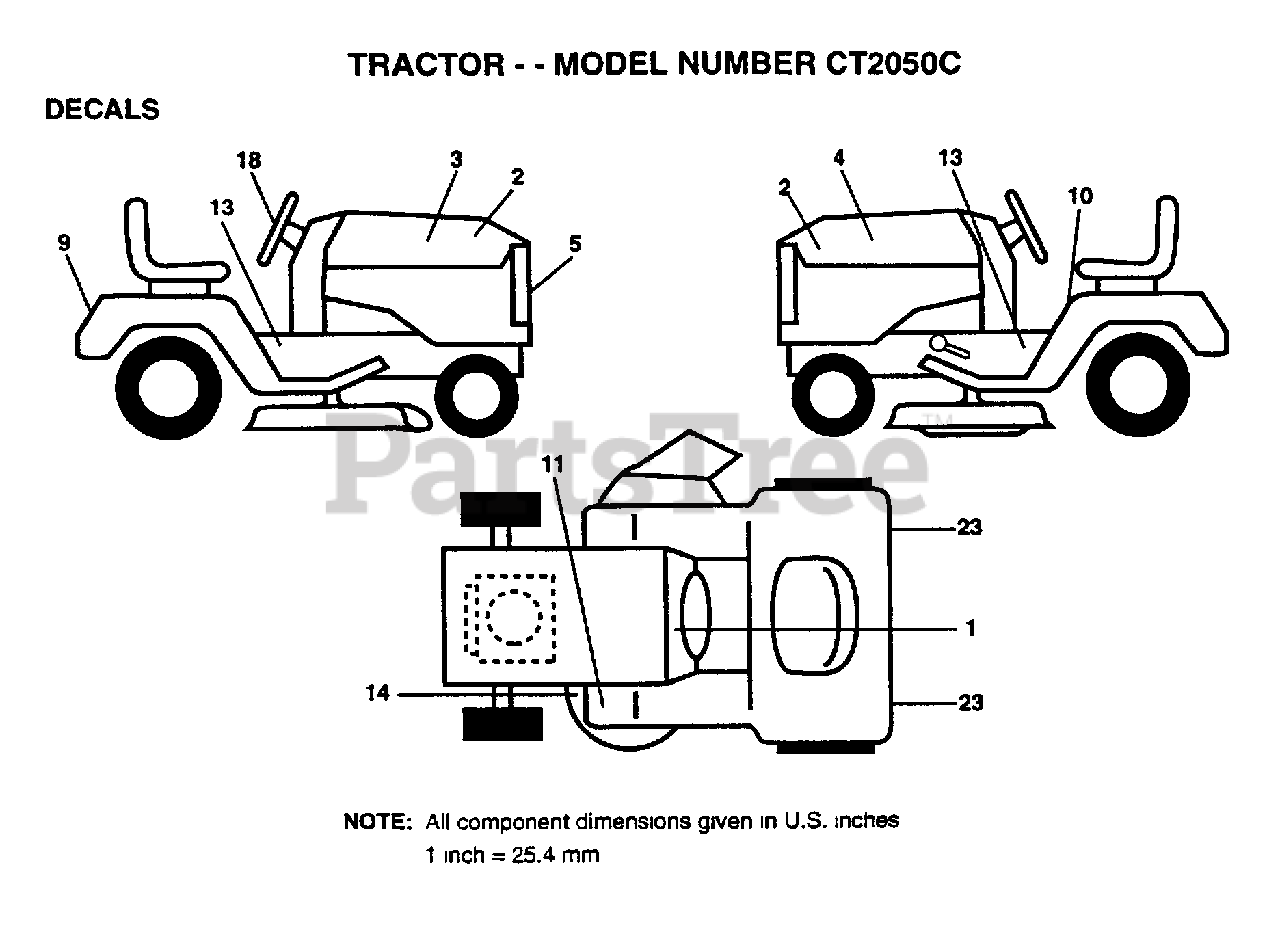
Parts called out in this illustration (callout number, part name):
1	DECAL.DASH.INST.
2	DECAL.HOOD.INS
3	DECAL.HOOD.RH.
4	DECAL.HOOD.LH.
5	DECAL.GRILLE
9	DECAL.FENDER
10	DECAL
13	DECAL.CHASSIS 6SP
14	"DECAL.V.BELT.44"""
18	DECAL INST STRWHL
23	REFLECTOR-TAIL YT
